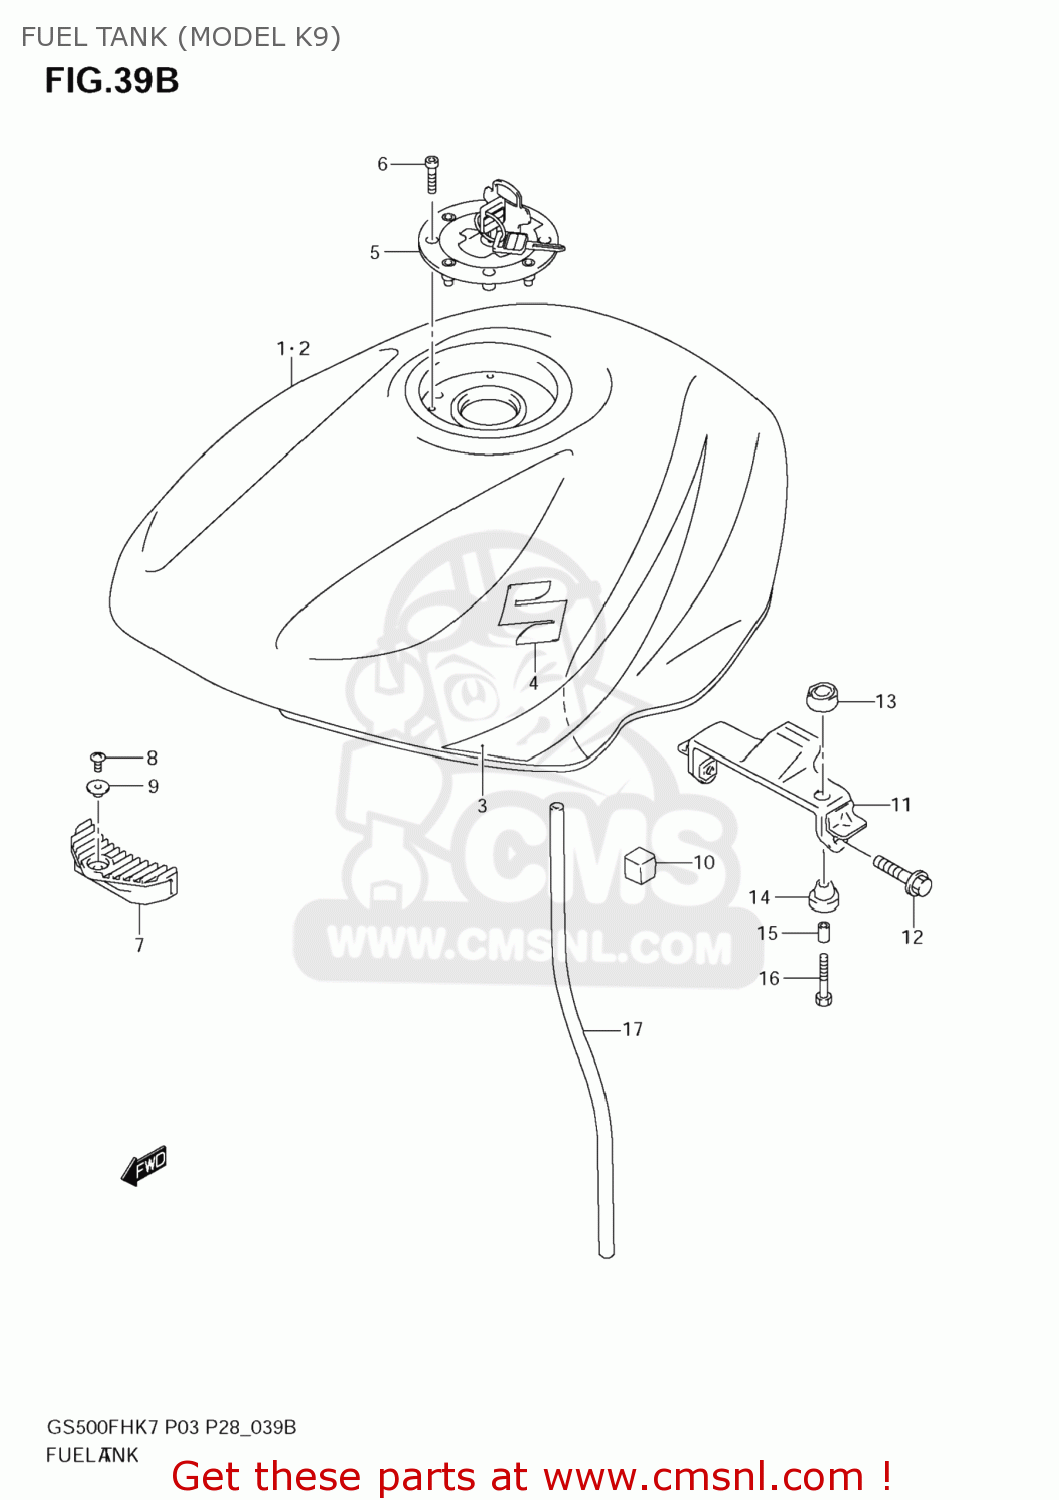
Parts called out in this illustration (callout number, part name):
1	TANK ASSY,FUEL(BLUE)
2	TANK ASSY,FUEL(BLUE)
3	TAPE SET,FUEL TANK
4	EMBLEM,S
5	CAP SET,FUEL TANK
6	BOLT(5X20)
7	CUSHION,FUEL TANK FR
8	SCREW, THROTTLE CABLE
9	WASHER
10	CUSHION,FUEL TANK SIDE
11	BRACKET, REAR
12	BOLT
13	CUSHION
14	CUSHION
15	SPACER(6.5X9X18)
16	BOLT(6X30)
17	HOSE, DRAIN
